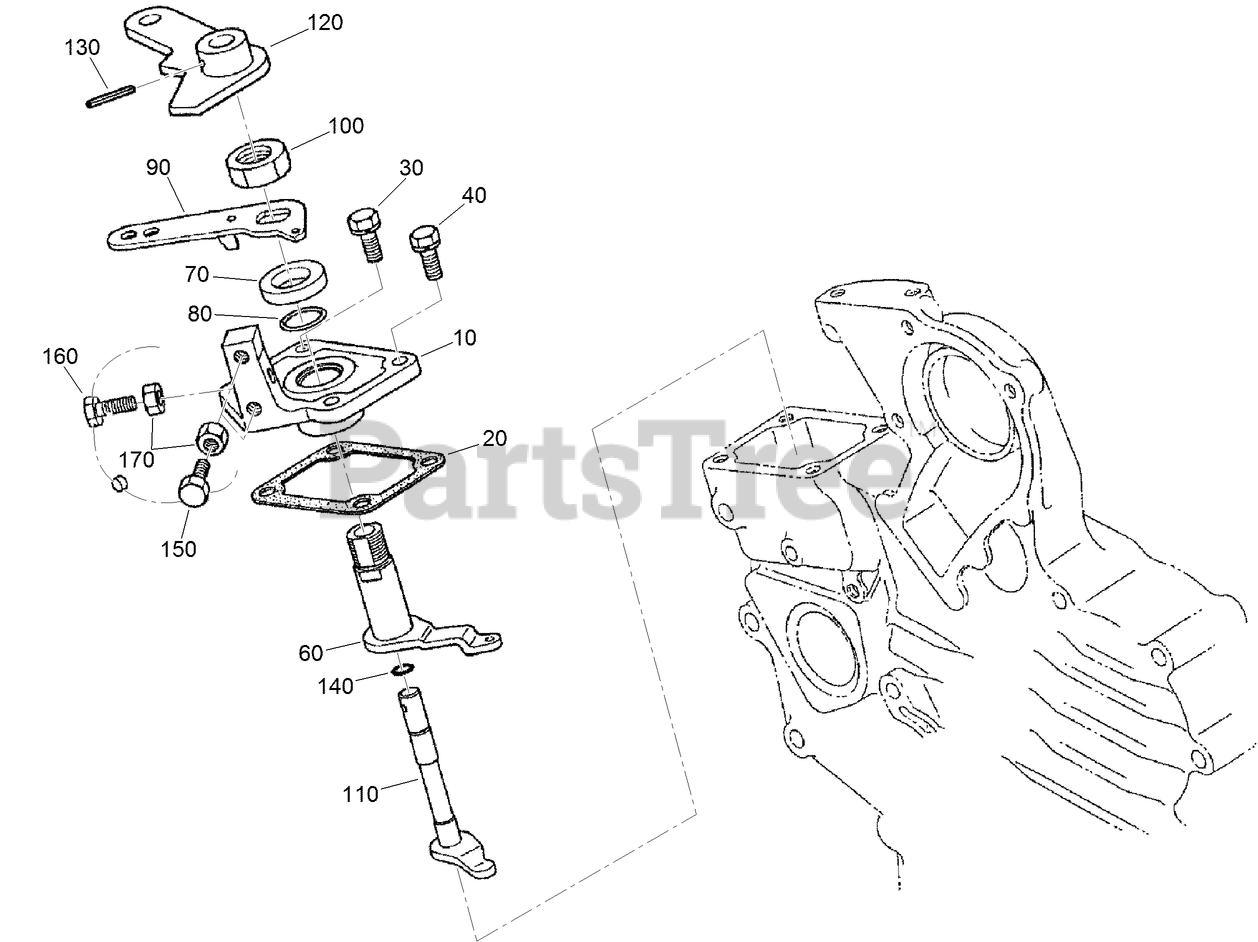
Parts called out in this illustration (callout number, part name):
10	PLATE-CONTROL, SPEED
20	GASKET-PLATE, CONTROL
30	BOLT-FLANGE
60	LEVER-GOVERNOR
70	COLLAR
80	O-RING
90	LEVER-CONTROL, SPEED
100	NUT-CONTROL, SPEED
110	SHAFT-LEVER
120	LEVER-STOP, ENGINE
130	PIN-SPRING
140	O-RING
150	SCREW-STOPPER
